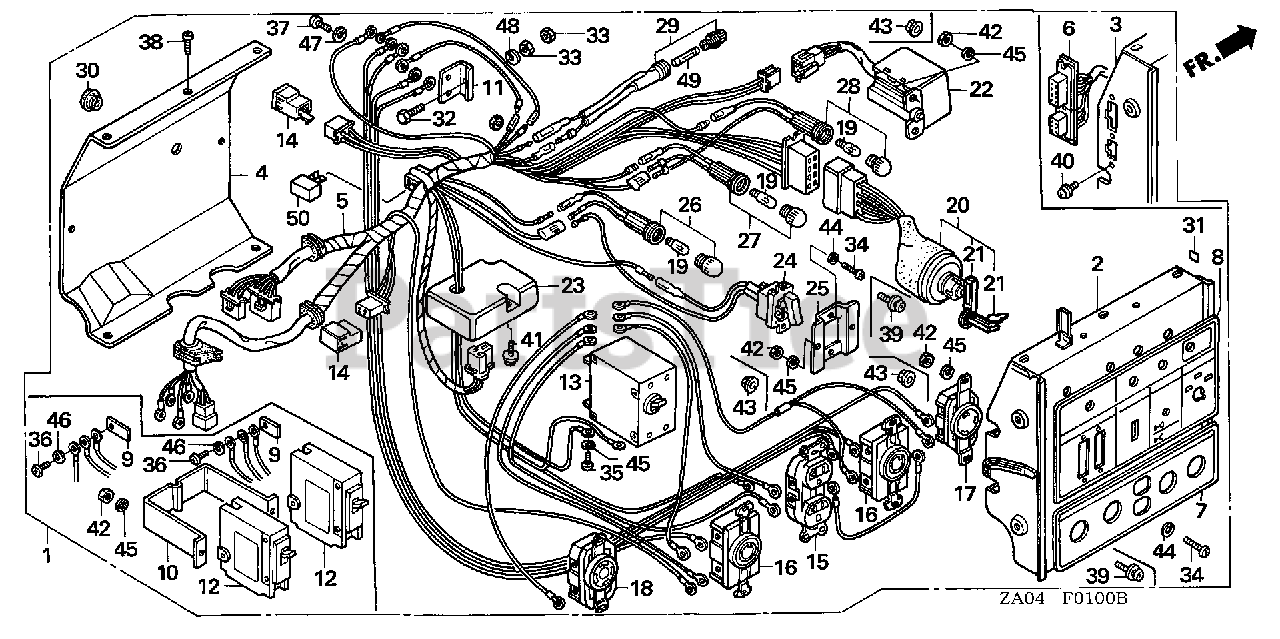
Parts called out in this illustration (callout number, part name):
1	BOX ASSY., CONTROL *NH105* (MAT BLACK)
3	PANEL, FR.
4	COVER
6	WIRE HARNESS
7	MARK, RECEPTACLE PANEL
8	MARK, SWITCH PANEL
11	PLATE, GROUND
13	BREAKER, CIRCUIT (27A)
14	STACK ASSY., DIODE (2.7A)
16	RECEPTACLE (20A/125V) (NOT AVAILABLE)
17	RECEPTACLE (3-PRONG) (30A/125V)
18	RECEPTACLE (30A/125-250V)
19	BULB (24V2W)
20	SWITCH ASSY., COMBINATION
21	KEY
22	RELAY, ALERT
23	CONTROL UNIT, IDLE
24	SWITCH ASSY., IDLE CONTROL
25	STAY, SWITCH
26	SOCKET ASSY., PILOT LAMP
27	SOCKET ASSY., LAMP
28	SOCKET ASSY., LAMP
29	HOLDER, FUSE
30	GROMMET, TOP COVER
31	MARK, GROUND
32	BOLT, HEX. (8MM)
33	NUT, HEX. (8MM)
35	SCREW, PAN (4X8)
37	SCREW, PAN (6X12)
38	SCREW-WASHER (4X8)
39	SCREW-WASHER (3X6)
40	SCREW-WASHER (4X10)
41	SCREW-WASHER (5X10)
43	NUT, FLANGE (4MM)
47	WASHER, SPRING (6MM)
48	WASHER, SPRING (8MM)
49	FUSE B (15A)
50	RECTIFIER ASSY., SILICON (STANLEY)
50	RECTIFIER ASSY., SILICON (SHINDENGEN)
